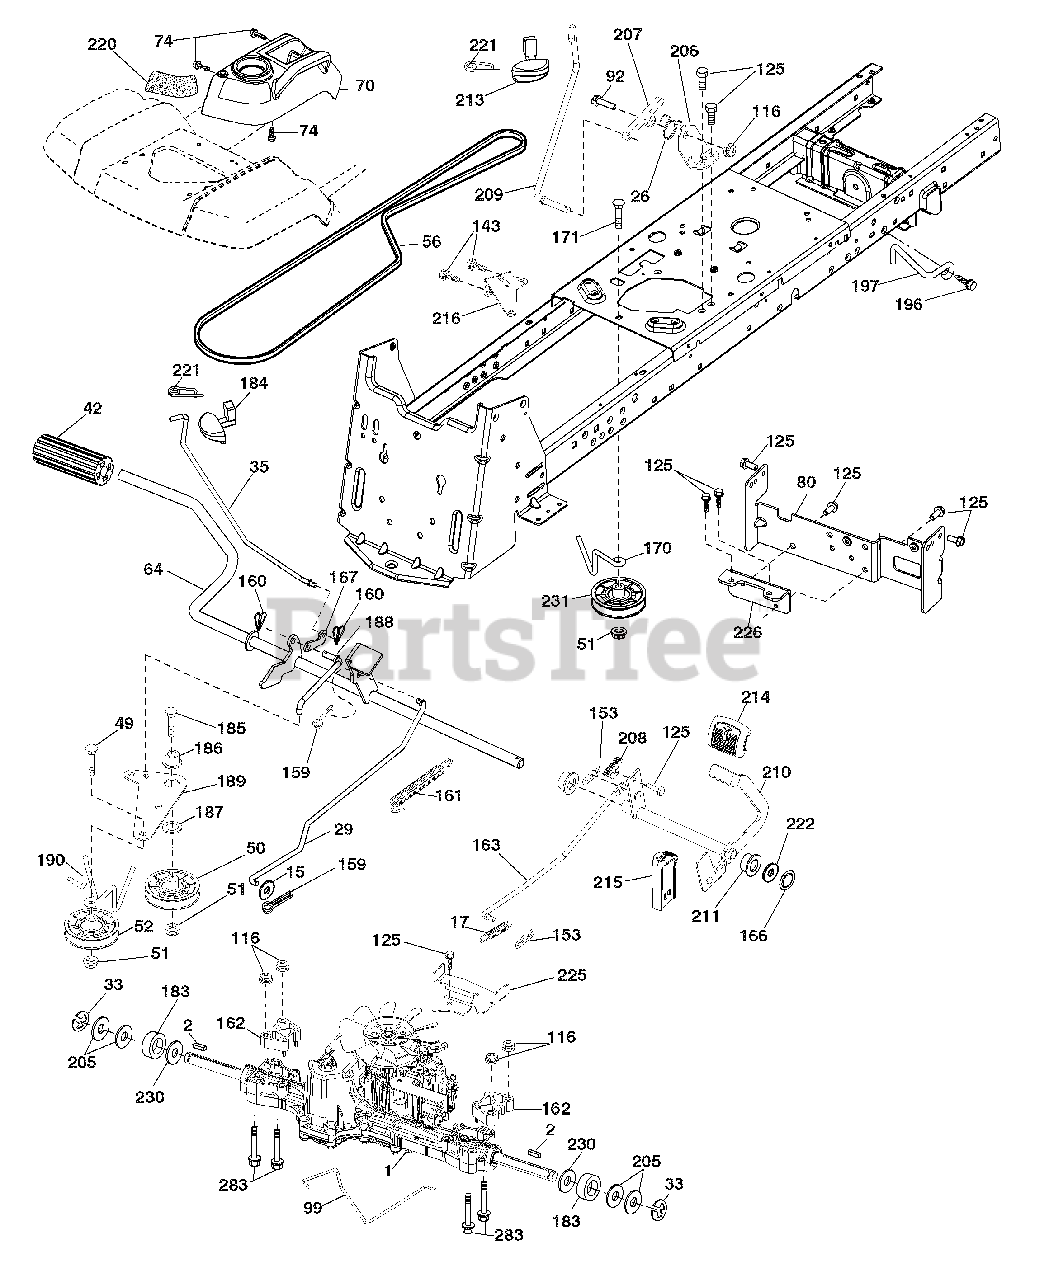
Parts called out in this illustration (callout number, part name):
1	Transaxle, TUFFTORQ K46
15	Washer 13/32 x 13/16 x 16 Ga.
17	Spring, Brake
26	Spring Return Cruise
29	Rod, Brake
35	Rod, Brake, Park
42	Cover, Foot Pedal
50	Pulley Idler Flat
51	Lock Nut 3/8-16
52	Idler V-Groove 910" Offset
56	V-Belt, Drive
64	Shaft Asm. Pedal Brake Control
70	Console Asm.
74	Screw 1/4 x 1/2
80	Strap Torque
92	Bolt Fin Hex 5/16-18 unc x 1.25
99	Spring Rod Bypass
116	Nut Lock Hex Flange 5/16-18
125	Screw 5/16-18 x 3/4
143	Screw Thdrol 5/16-18 x 1/2
153	Retainer Spring
159	Pin Cotter 1/8 x 3/4
160	Retainer Clip
161	Spring, Return, Clutch
162	Spacer Transaxle
163	Rod Pedal Control
166	Nut Push .625
167	Latch Brake Parking
170	Keeper Belt Centerspan
171	Bolt 3/8 - 16 x 2-3/4 Gr. 5
183	Spacer Split
184	Handle Parking Brake
185	Bolt Rdhd Sqnk 3/8-16 x 2-1/2
186	Spacer Retainer
187	Washer
188	Link Clutch Ground Drive
189	Bellcrank Ground Drive
190	Keeper Bellcrank Ground Drive
196	Screw 3/8-16 x 1
197	Bracket Clutch Anti-Rotation
206	Bracket Mount Latch Cruise
207	Latch Control Cruise
208	Gear Sector Control Cruise
209	Rod Control Cruise
210	Rocker Asm. Pedal Control
211	Bearing Nylon
213	Knob Control Cruise
214	Pedal Forward
215	Pedal Reverse
216	Bracket Pulley Idler
220	Reflector RH
221	Retainer Spring Clip Handle
222	Washer 21/32 x 1-1/4 x 10 Ga.
225	Keeper Belt Trans.
226	Bracket Mount Touque
231	Idler V-Groove Pulley
283	Bolt Hex WSHRHD 5/16-18 x 4.25 Gr.5
